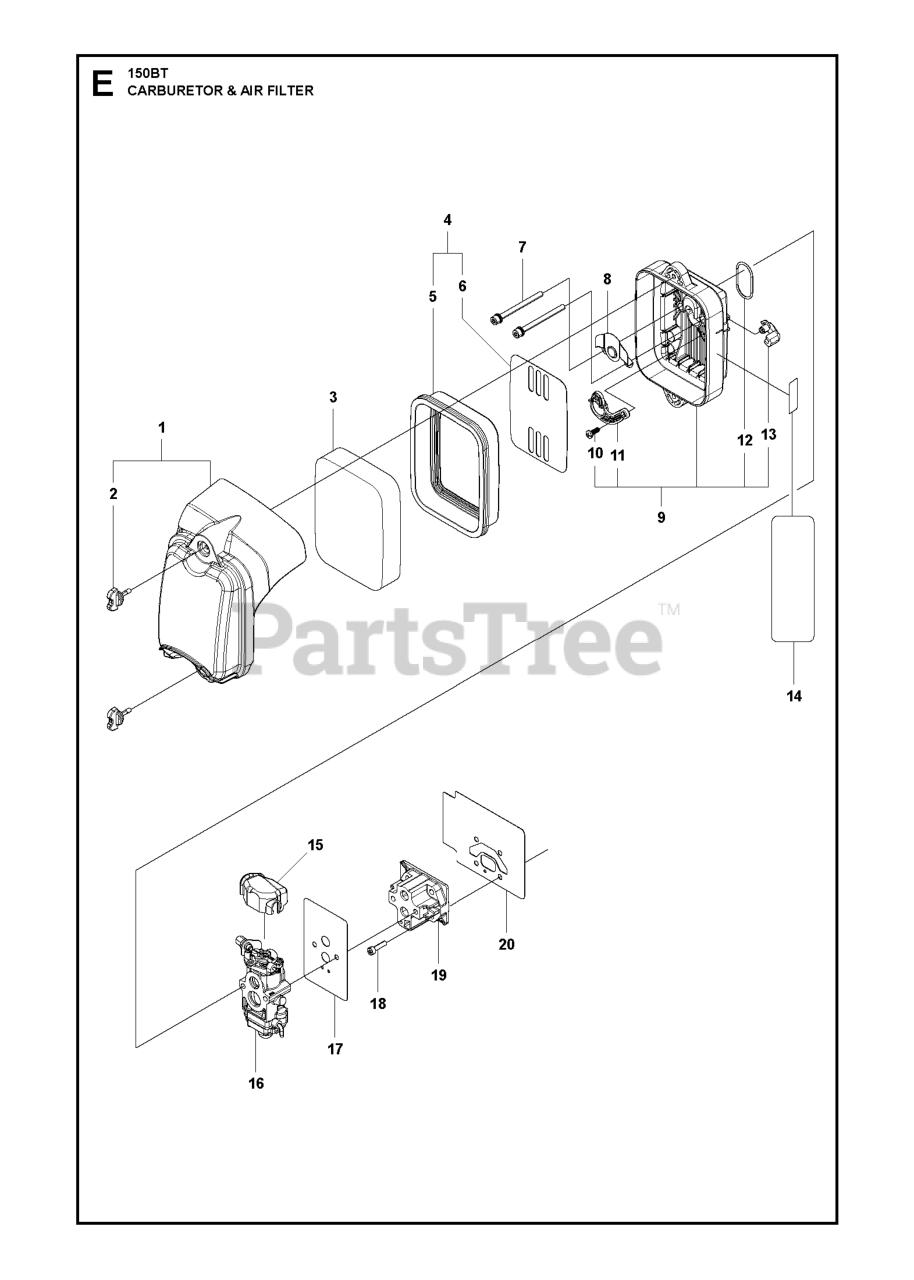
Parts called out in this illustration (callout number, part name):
3	AIR FILTER
3	AIR FILTER, ELEMENT
9	AIR FILTER HOLDER ASSY
10	SCREW
11	PLATE
12	O-RING
13	LEVER
14	LABEL,CHOKE
16	CARBURETOR
18	BOLT
19	INSULATION
20	GASKET,INSULATOR
